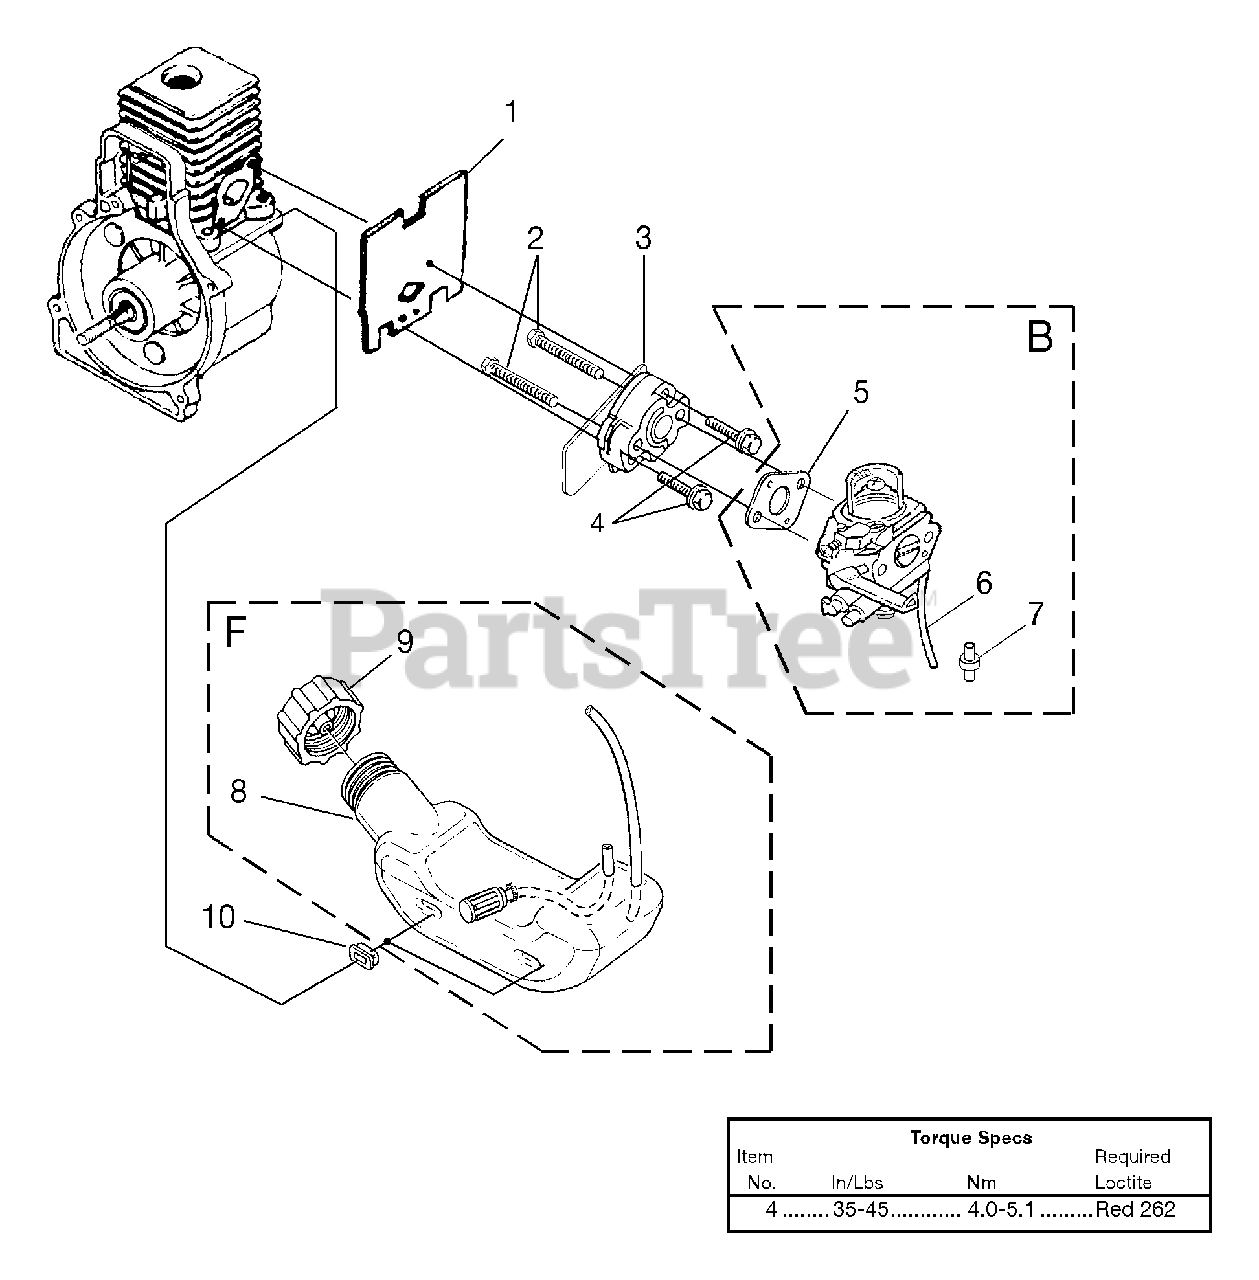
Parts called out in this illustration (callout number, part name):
1	GASKET-Heat Dam
2	SCREW-Machine (10-24 X 2 1/4")
3	HEAT DAM
4	SCREW-Sems (10-24 X 1")
5	GASKET-Carburetor
6	TUBING-Rubber
7	FITTING-Inline Fuel
8	FUEL TANK
9	FUEL CAP
10	BUMPER-Rubber
B	CARBURETOR KIT
F	FUEL TANK ASSY.
